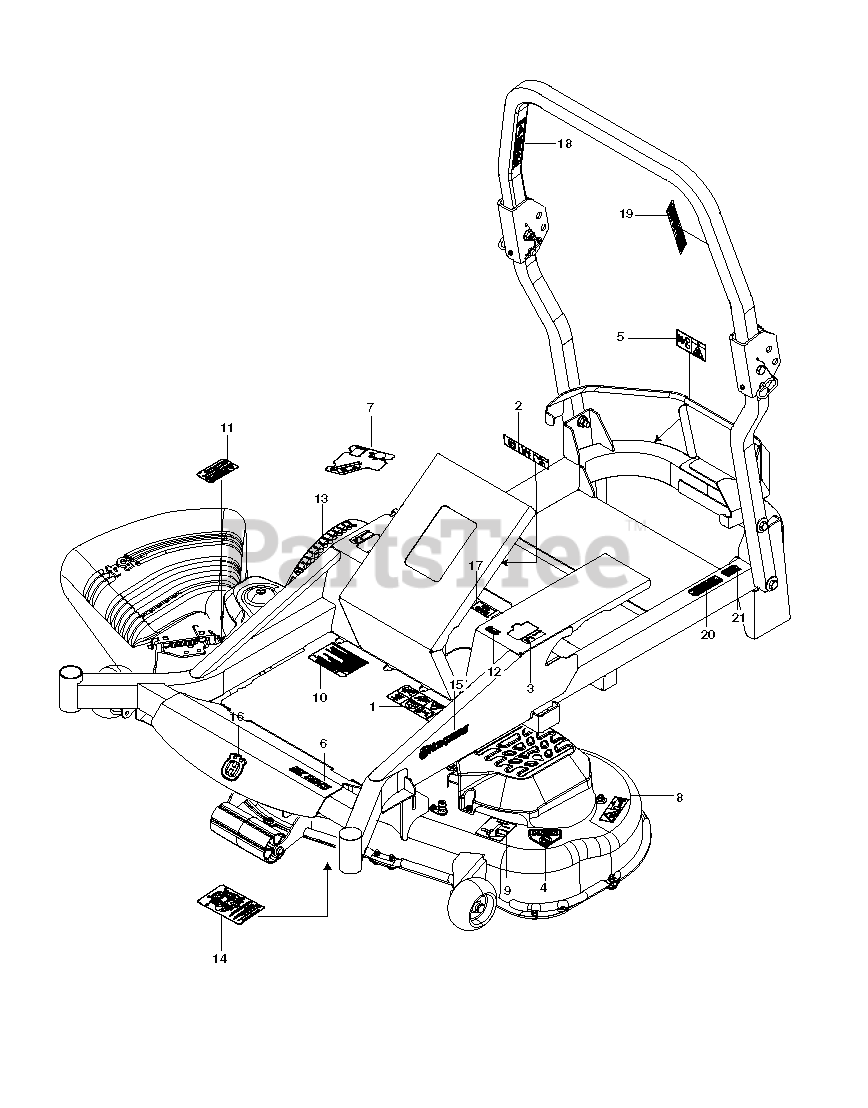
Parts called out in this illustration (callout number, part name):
1	DECAL, WARNING
2	EURO DECAL-BATTERY WARNIN6
3	DECAL, MOTION CONTROL
4	DECAL, CPSC
5	DECAL, BELT DRIVE
6	DECAL, MZ5424S
7	DECAL, CONSOLE HUS
8	DECAL, EURO SEVERING
9	DECAL, BELT ROUTING
10	DECAL, WARNING
11	DECAL.DECK.6MIL./DEF.SHLD.WARN
12	DECAL, F.S.T.
13	DECAL, HEIGHT ADJUST
14	DECAL, SERVICE
15	RP.DECAL.BADGE.170MM.TEXTLOGO
16	DECAL.AUGER.HUSQ.CROWN.SNOW
17	DECAL HYDROGEAR ZT-3100
18	DECAL, ROPS, WARNING
19	DECAL ROPS
20	DECAL, WARNING SPARK ARRESTOR
21	DECAL, PROP. 65
